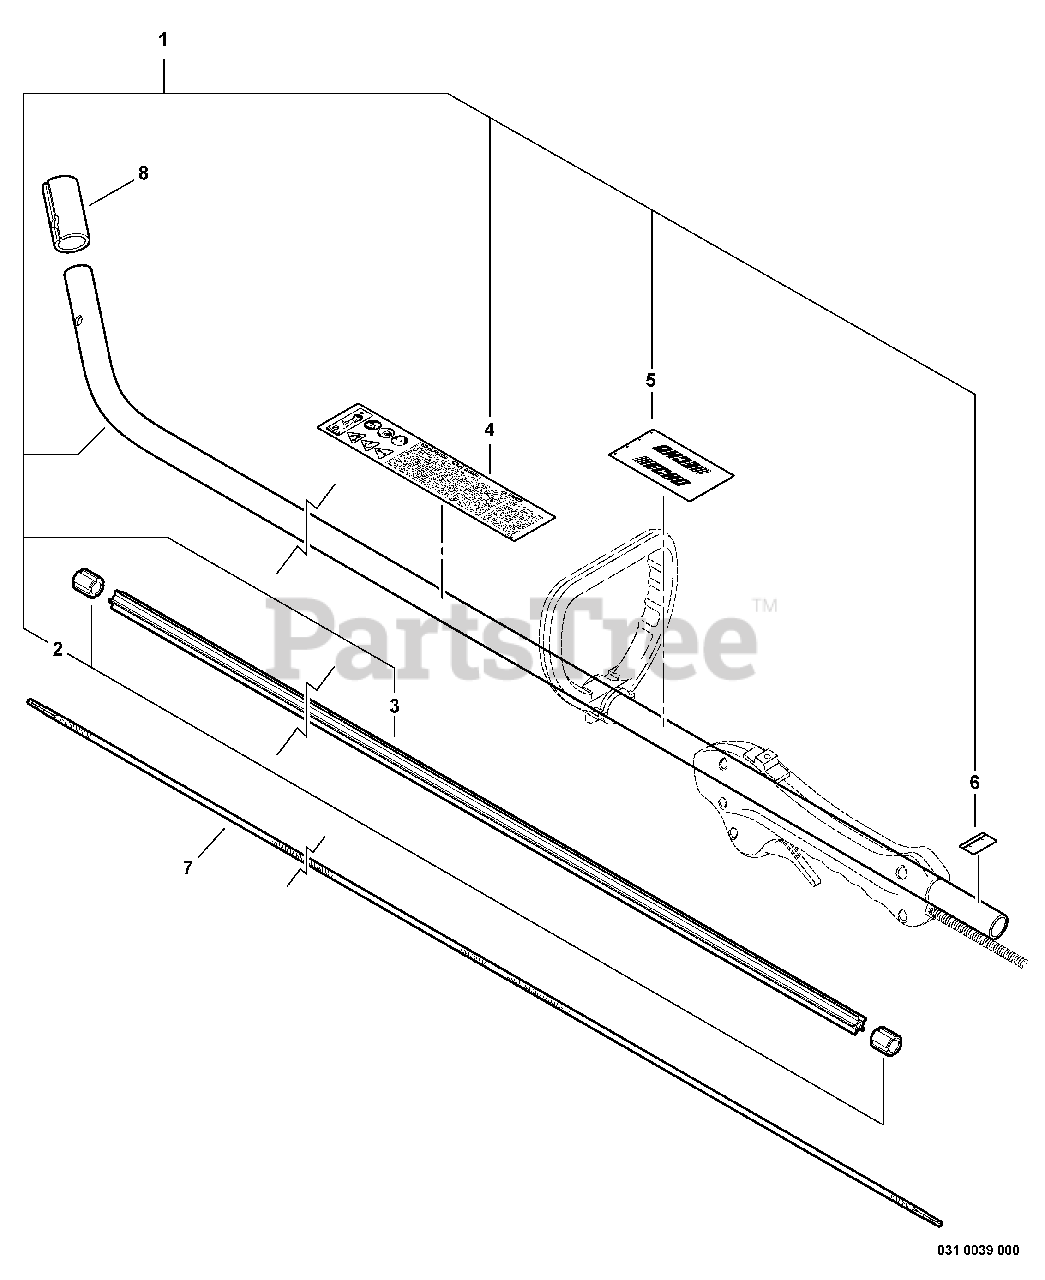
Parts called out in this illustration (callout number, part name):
1	MAIN PIPE ASSY
3	LINER - FLEXIBLE
4	LABEL, CAUTION
5	LABEL, HANDLE LOCATION
6	LABEL - ALIGNMENT
7	DRIVESHAFT - FLEXIBLE L= 1522
